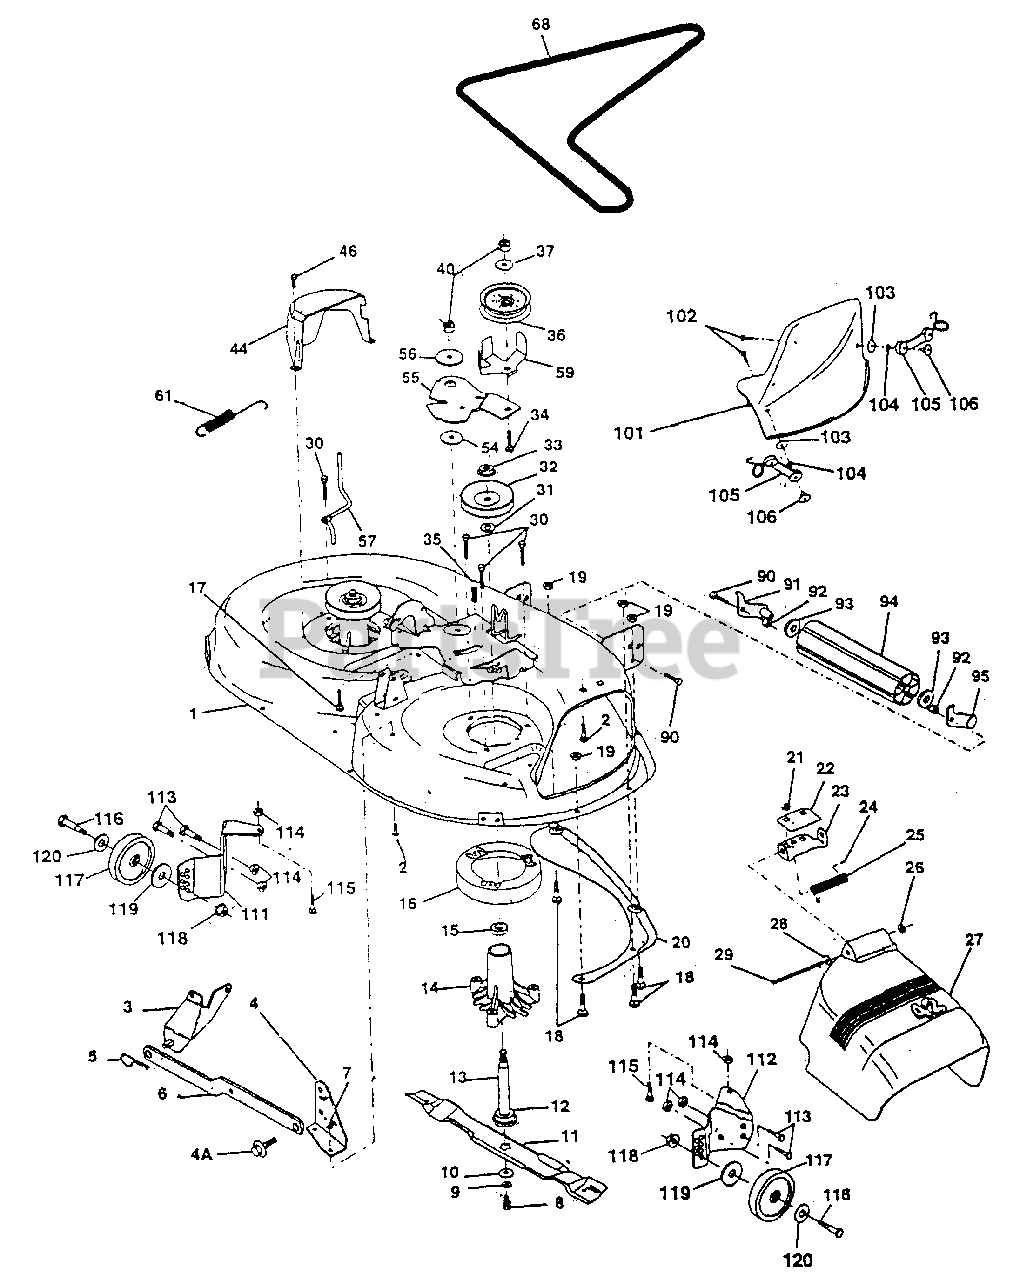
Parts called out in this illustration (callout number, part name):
1	Deck Asm MWR 42" weldment
2	Bolt Rdhd Sqnk 5/16-18unc X3/4
3	Bracket Asm Fr Sway Bar 38/42
4	Bracket Asm Deck 42" sway Bar
4A	Bolt Shoulder
5	Retainer Spring
6	Arm Suspension Rear
7	Locknut-hex W/ins 5/16-18unc P
8	Bolt 3/8-24x1 25 Gr8 Patched
9	Washer Lock Hvy 3/8 Unplated
10	Washer-Hard Blade Mower Vented
11	Blade Mower Mulching 42"
12	Bearing Ball #6204 (Mandrel)
13	Shaft Asm W/lower Bearing
14	Housing Mandrel Vented(machd)
15	Bearing Ball Mandrel
16	Stripper Mower Vented
17	Bolt Rdhd Sqnk 3/8-16 X 2
18	Bolt Carr 5/16-18 X 5/8
19	Locknut-hex W/ins 5/16-18unc P
20	Baffle Vortex 42
21	Nut Lock 5/16-18
22	Stiffener Bracket 42" deck
23	Bracket Deflector Mower 42"
24	Cap Sleeve 80x 112 Blk Mower
25	Spring Torsion Deflector 2 52
26	Nut Push Phos & Oil
27	Shield Deflector Mower 42" Blk
28	Washer 11/32 X 5/8 X 16 Ga
29	Rod Hinge 42" 6 75 Wlg
30	Screw Thdrol Hex Hd Zinc Mwr.
31	Washer Spacer Mower Vented
32	Pulley Mandrel 42"
33	Nut 9/16top Lock Flng Cntr
34	Bolt Rdhd 3/8-16uncx2-3/4 Gr5
35	Fastner Christmas Tree
36	Pulley Idler Flat 3 060
37	Washer 13/32 X 13/16 X 16 Ga.
40	Nut Lock 3/8-16 Unc
41	Spacer Spring Stop Idler
44	Guard Mandrel LH Black
46	Screw Thdrol 1/4-20x5/8
54	Washer Hardened
55	Arm Idler 42" mower LT/YT
56	Spacer Retainer Pm Mower
57	Guide, Belt
58	Guard, Belt
61	Spring Ext. Elect
68	V-Belt Mower 42"
90	Bolt Fin Hex 3/8-16unc X 1
91	Bracket Asm Noseroller LH
92	Nut Crownlock 3/8-16 Unc
93	Washer 17/32 X 7/8 X 16 Ga
94	Roller Nose 38 & 42
95	Bracket Asm Noseroller RH
101	Cover Mulching 42" Blk
102	Screw
103	Washer Lock #10
104	Washer #10
105	Latch Asm Bagger
106	.327/.304 Nut Weld #10-24
111	Bracket Wheel Gauge Lh 42" Deck
112	Bracket Gauge Wheel Rh 42" Deck
113	Bolt Hex Hd 5/16 - 18 UNC x 3/4
114	Nut Keps 5/16 - 18 UNC
115	Bolt Carriage 5/16 - Unc x 1/2
116	Bolt Shld "A" 2.41 "B" 1.66
117	Wheel Gauge blk. 4.93
118	Nut Centerlock 3/8 - 16 UNC
119	Washer 3/8 x 7/8 x 14 Ga.
120	Washer 17/32 x 15/16 x 12 Ga.
